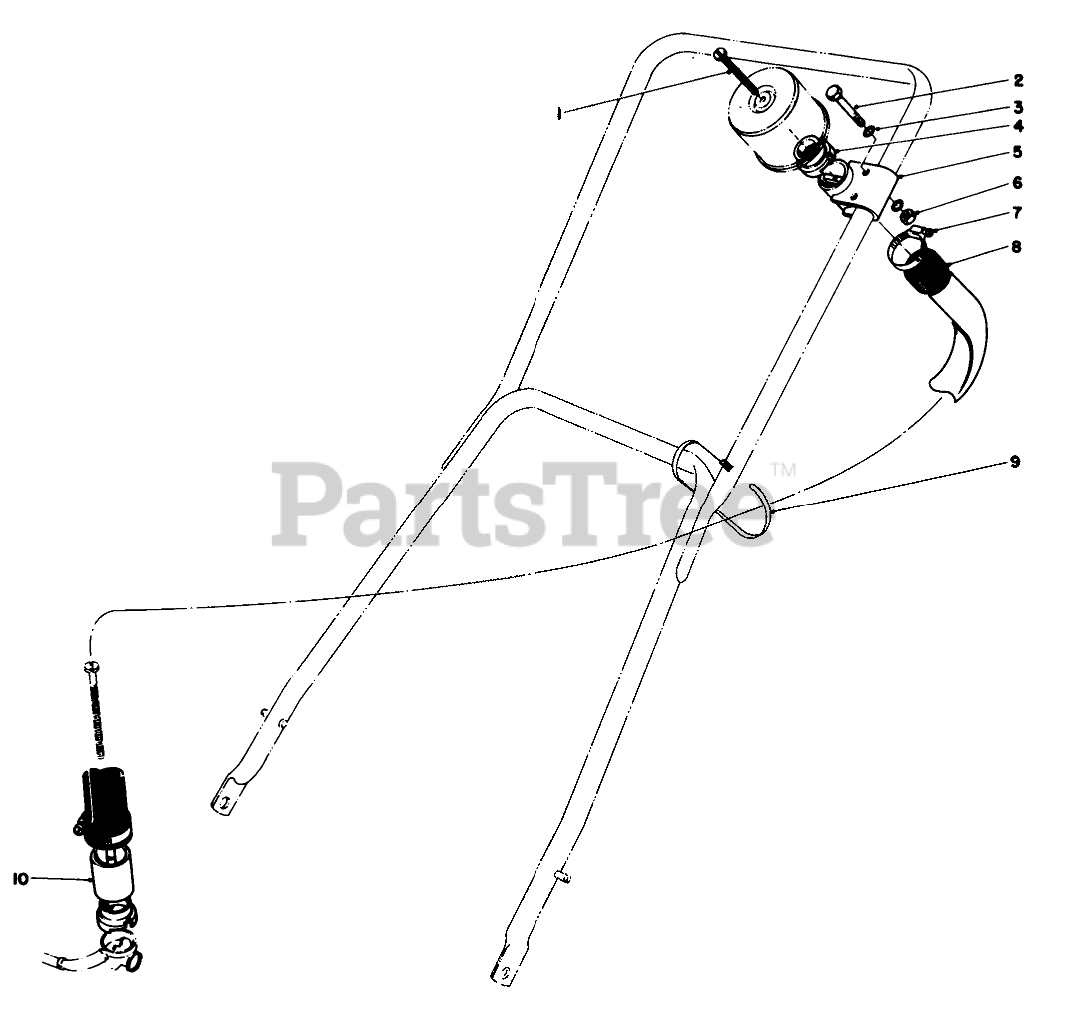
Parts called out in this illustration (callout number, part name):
1	Pan Hd. Machine Screw
2	SCREW-HH
3	WASHER-PLAIN
4	GASKET
5	Mounting Bracket Air Cleaner
6	NUT-HEX
7	CLAMP-HOSE
8	Hose Air Cleaner
9	TIE-CABLE
10	HOSE COUPLING WA B
